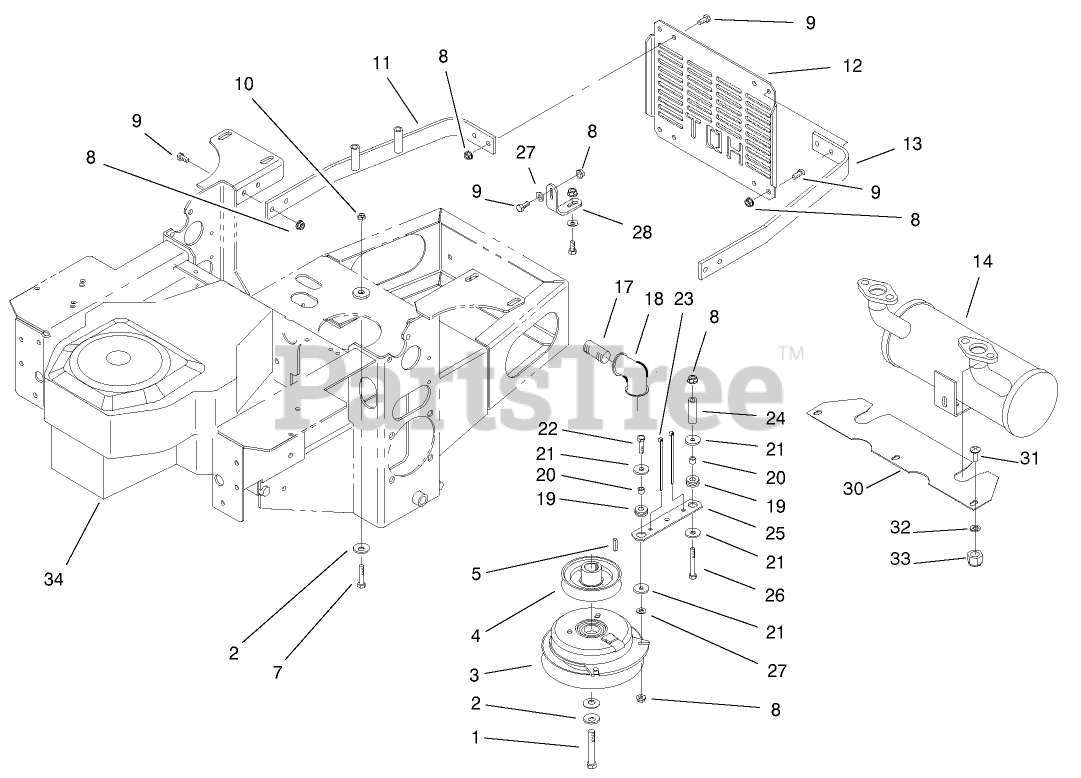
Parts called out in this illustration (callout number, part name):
1	SCREW-HH
2	Disc-Spring
3	Clutch
4	Sheave-Pump Drive
5	Key
6	Spacer-Crankshaft
7	SCREW-HH
8	NUT-HF
9	SCREW-HH
10	NUT-HF
11	Strap-Guard, Engine
12	Shield-Guard, Engine
13	Strap-Guard, Engine
14	Muffler
17	Pipe Nipple
18	Elbow
19	Grommet
20	Spacer
21	Washer
22	SCREW-HH
23	Tie-Plastic
24	Bushing-Mount, Seat
25	Strap
26	SCREW-HH
27	WASHER-FLAT
28	Bracket-Muffler
30	Shield-Heat
31	BOLT-CARR
32	WASHER-PLAIN
33	NUT-LOCK, NI
34	Engine-23hp Kohler CV23-75526
